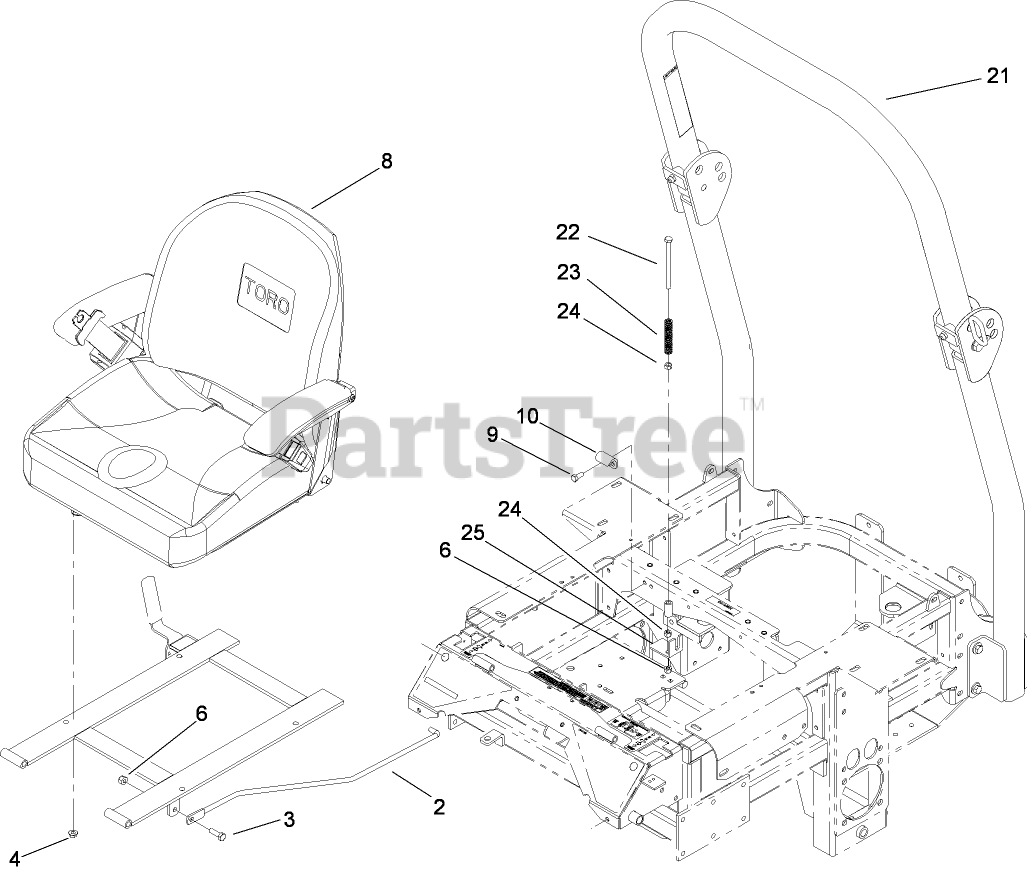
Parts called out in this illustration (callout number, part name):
2	ROD-PROP, SEAT
3	SCREW-HH
4	NUT-HF
6	NUT-LOCK, NI
8	SEAT ASM
9	SCREW-HH
10	Catch-Latch, Seat
21	ROPS KIT
22	SCREW-HH
23	SPRING-SWITCH, SEAT
24	NUT-HEX
25	PLATE-SWITCH, SEAT
